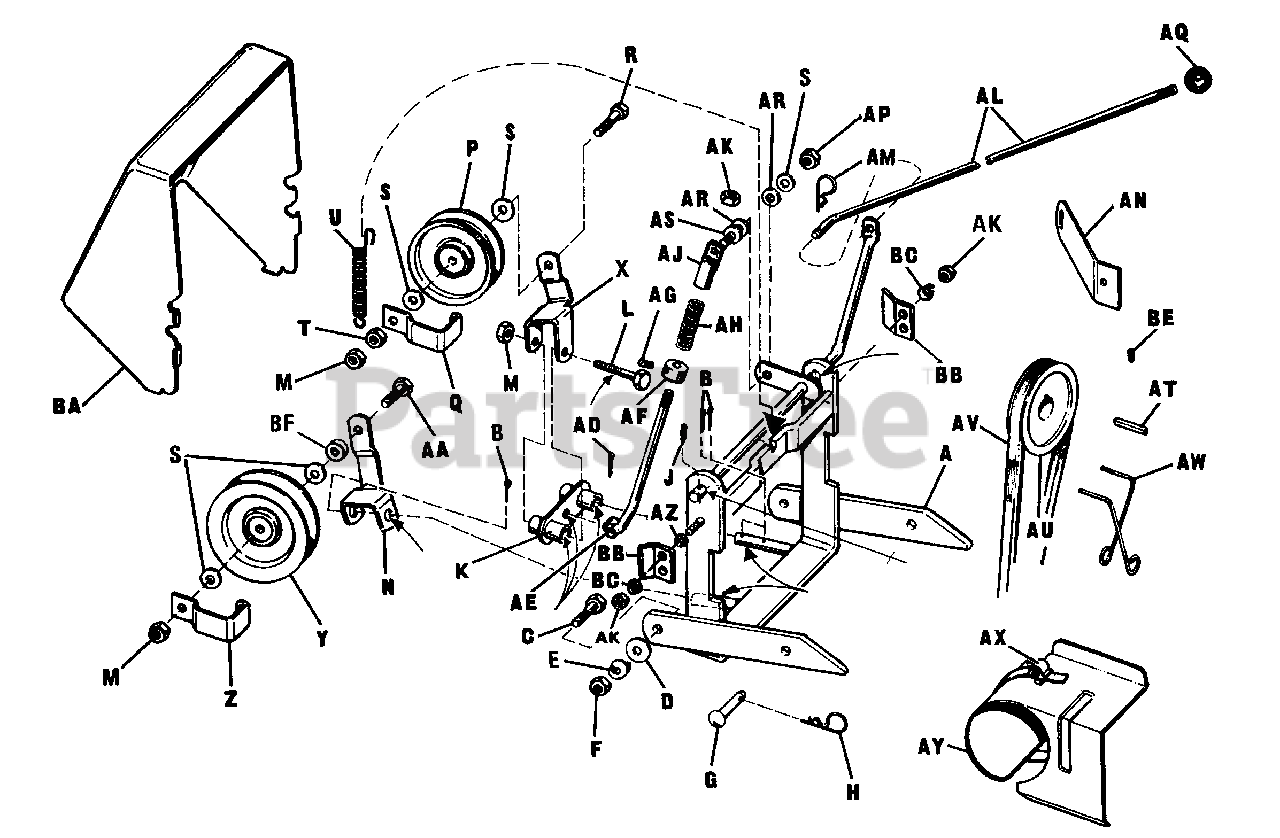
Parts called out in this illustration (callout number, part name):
A	Hitch Assembly
B	Cotter Pin, 1/8" Dia. x 1"
C	Hex. Cap Screw
D	Plain Washer, 3/8"
E	Spring Washer, 3/8"
F	Full Lock Hex Nut, 3/8"-24
G	Pin
H	Spring Clip
J	Cotter Pin, 1/8" Dia. x 1
K	Lever Ass'y Idler
L	Hex. Cap Screw
M	Full Lock Hex. Nut, 3/8"-16
N	Idlers Bracket
P	Idler Pulley
Q	Guide Belt
R	Hex. Cap Screw, 3/8"-16 x 1-1/2"
S	Plain Washer, 5/16"
T	Hex. Jam Nut
U	Return Spring
X	Idler Bracket
Y	Idlers Pulley
Z	Belt Guide
AA	Hex. Cap Screw, 3/8"-16 x 1-1/4"
AD	Cotter Pin, 3/32" Dia. x 3/4"
AE	Clutch Rod
AG	Set Sq. Hd. Cup Pt. Screw, 1/4"-20 x 3/8" lg.
AJ	Road Assembly Guide
AK	Hex. Full Lock Nut, 5/16"-18
AL	Clutch Handle
AM	Spring Clip
AP	Nut, Stop, 5/16"-18
AR	Nylon Washer
AU	Engine Pulley
AX	Deflector Clamp
AY	Heat Deflector
BA	Cover, Pulley
BB	Clip, Pulley Cover
BC	Spring, Concial
BE	Set Screw
